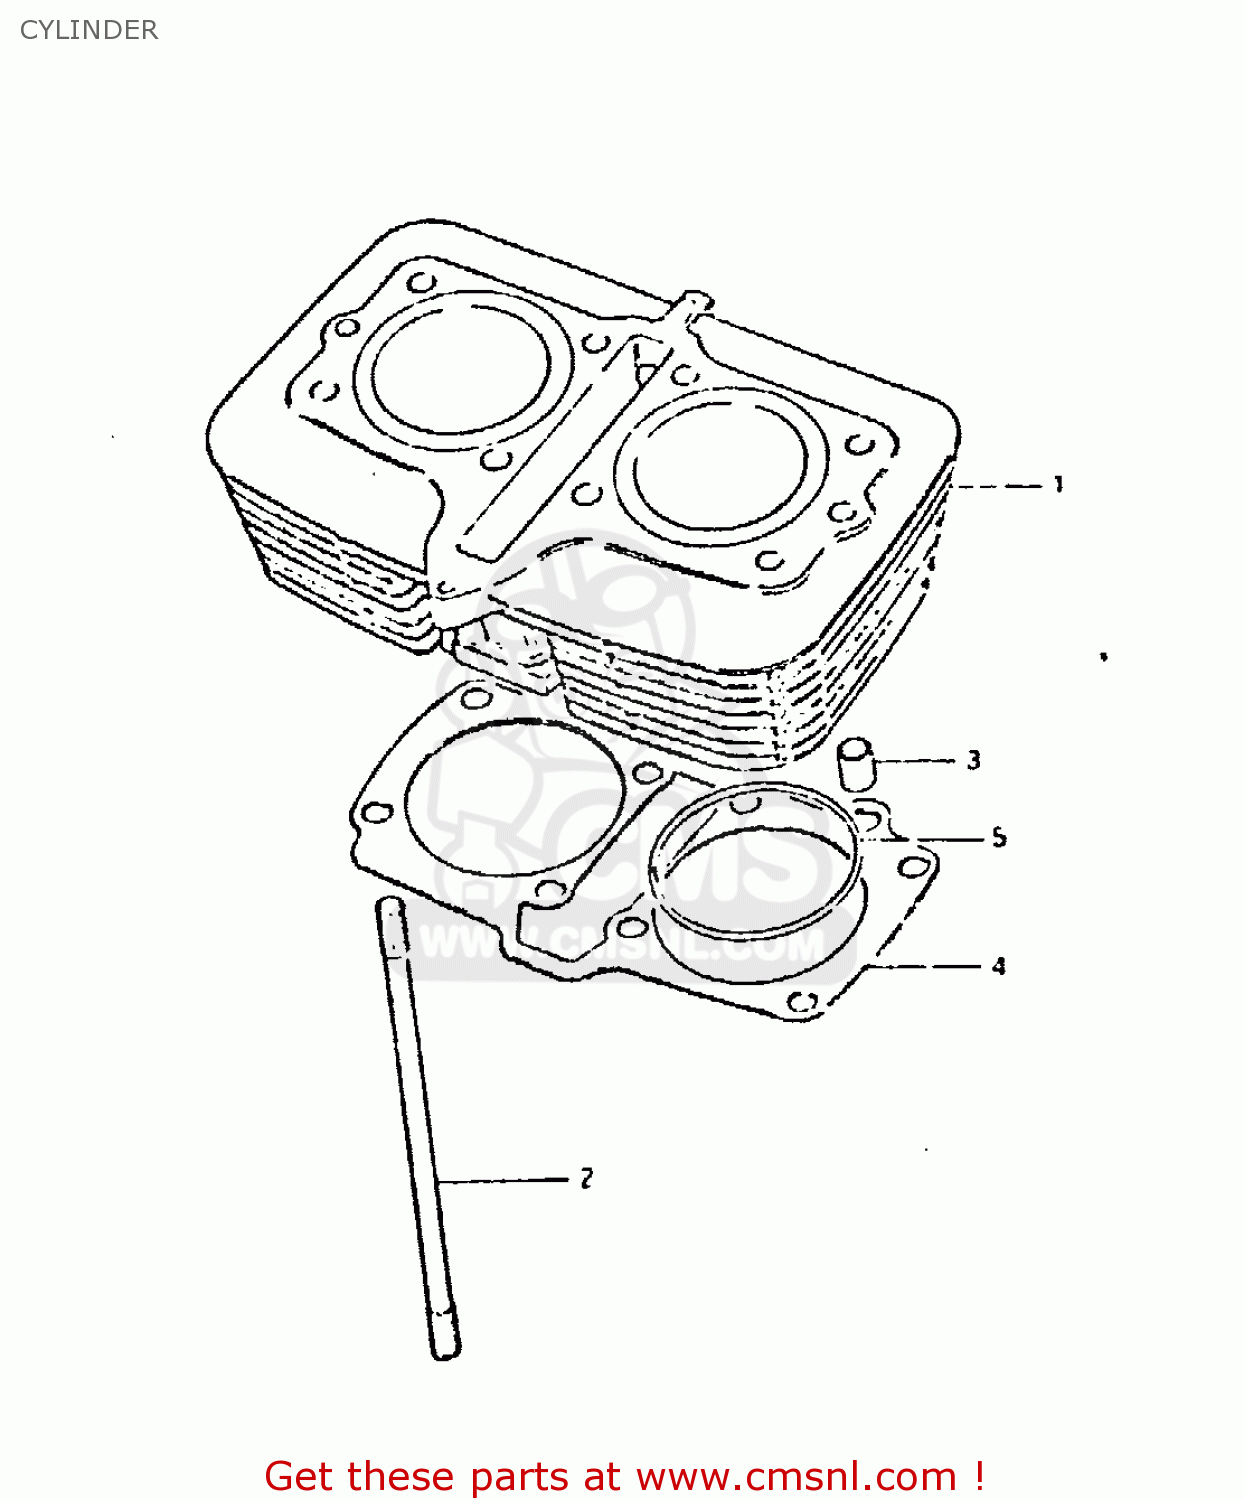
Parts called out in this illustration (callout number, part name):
1	CYLINDER
2	STUD
3	PIN
4	GASKET,CYLINDER (MCA)
5	O RING(D:2,ID:70)
